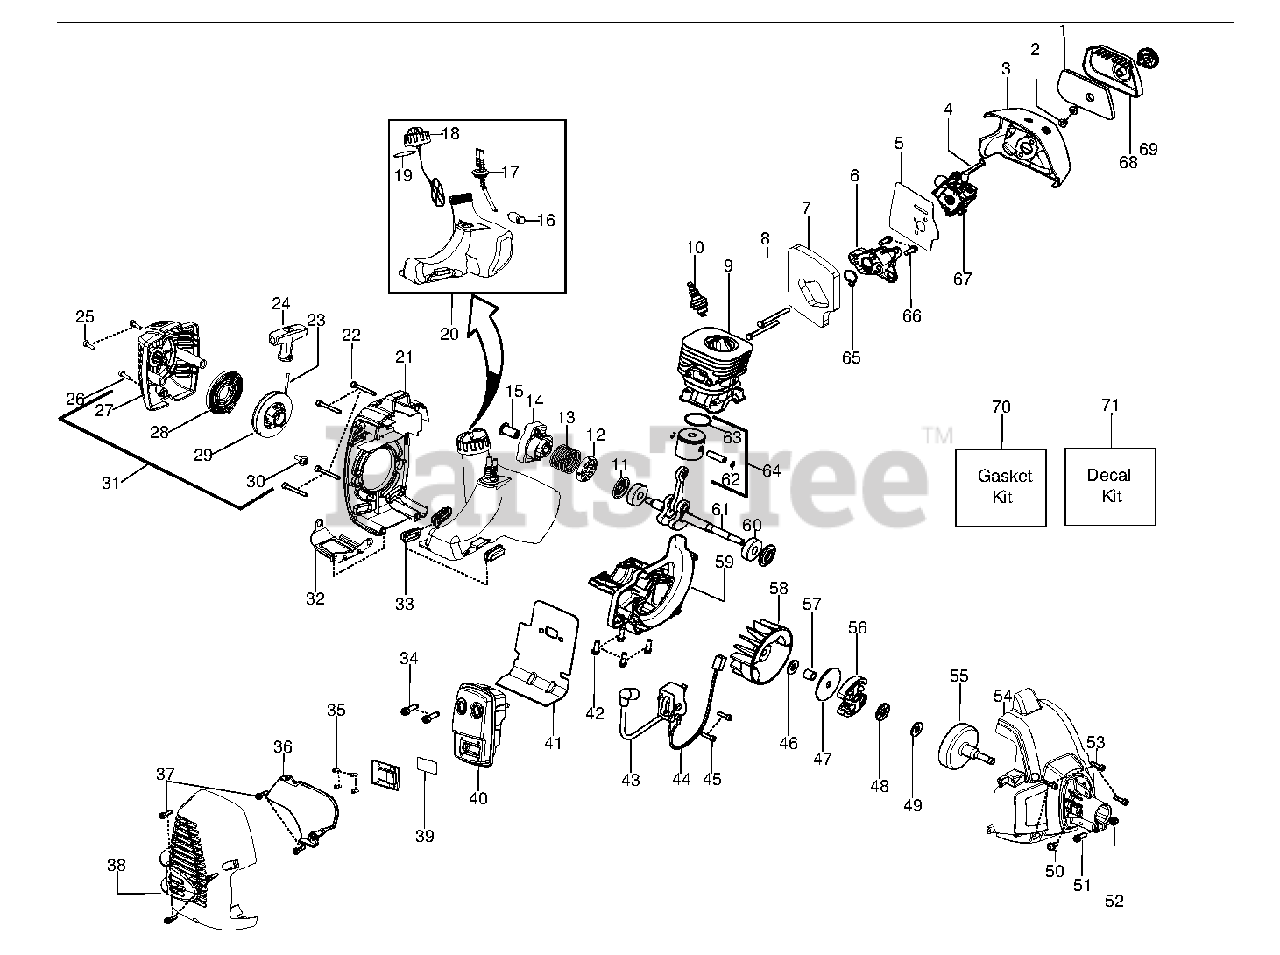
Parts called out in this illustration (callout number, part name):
1	FILTER AIRBOX
4	CHOKE LEVER
5	KIT GASKET CARB
6	CARB ADAPTOR
7	KIT GASKET 28CC
8	BOLT CARB ADAPTOR
9	CYLINDER
11	KIT SEAL CRANKSHAFT
12	WASHER STARTER
13	SPRING STARTER CUP
14	ASSY STARTER CUP
15	COUPLING STARTER
16	FUEL PICK-UP ASSY
17	KIT FUEL LINE
18	ASSY - FUEL CAP W/RETAINER
19	KIT GASKET 28CC
20	FUEL TANK ASSY
21	SHROUD REAR
24	HANDLE - STARTER
25	SCREW M5-0.8X30MM
26	SCREW M4 X 1.75 PT 16MM
28	%KIT STARTER SPRING
29	KIT STARTER PULLEY
32	PLATE WEAR
33	ISOLATOR FUEL TANK
34	BOLT MUFFLER
35	SCREW-6-19X5/16PLAST PA
36	SHIELD HEAT
37	SCREW M4 X 1.75 PT 16MM
39	KIT SPARK ARRESTOR SCREEN
40	ASSY-MUFFLER
41	KIT GASKET 28CC
42	B0LT, C/SHAFT 36/41
43	IGNITION MODULE
44	ASSY MODULE LEAD WIRE
45	SCREW M4 X .70 TT 16MM
46	WASHER CLUTCH
47	WASHER-CLUTCH
48	BEARING THRUST
49	WASHER THRUST
52	NUT HEX LOCK 10-24
53	SCREW M4 X .70 TT 16MM
55	ASSY-CLUTCH DRUM
56	%KIT CLUTCH ASSY
57	SPACER FLYWHEEL
59	CRANKCASE CASTING
60	BEARING RADIAL BALL (6201)
61	KIT CRANKSHAFT ASSY
62	WRIST PIN RET.
63	RING PISTON
64	KIT PISTON 28CC TRIMMER
65	KIT GASKET 28CC
66	B0LT, C/SHAFT 36/41
67	KIT CARB
68	COVER AIR BOX
69	ASSY - AIR BOX KNOB
70	KIT GASKET 28CC
